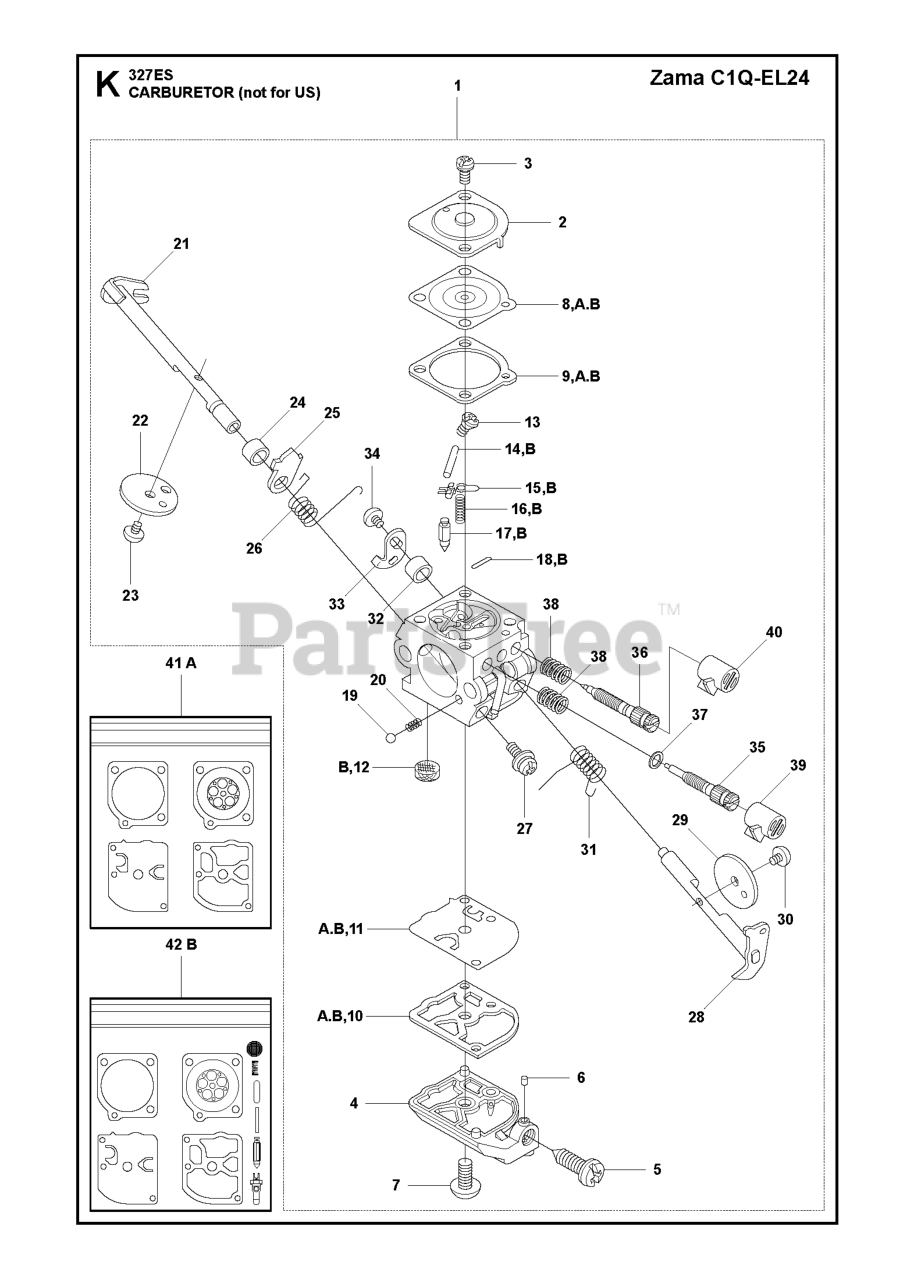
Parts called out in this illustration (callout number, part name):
1	CARBURETOR
11	PUMP DIAPHRAGM
14	PIN RETAINING SCREW
16	SPRING
17	INLET NEEDLE
21	CHOKE SHAFT
29	THROTTLE FLAP
31	SPRING THROTTLE
35	NEEDLE HIGH SPEED
36	LOW SPEED NEEDLE
38	SPRING
41	GASKET KIT (ZAMA GND39)
42	CARBURETOR KIT (ZAMA RB69)
